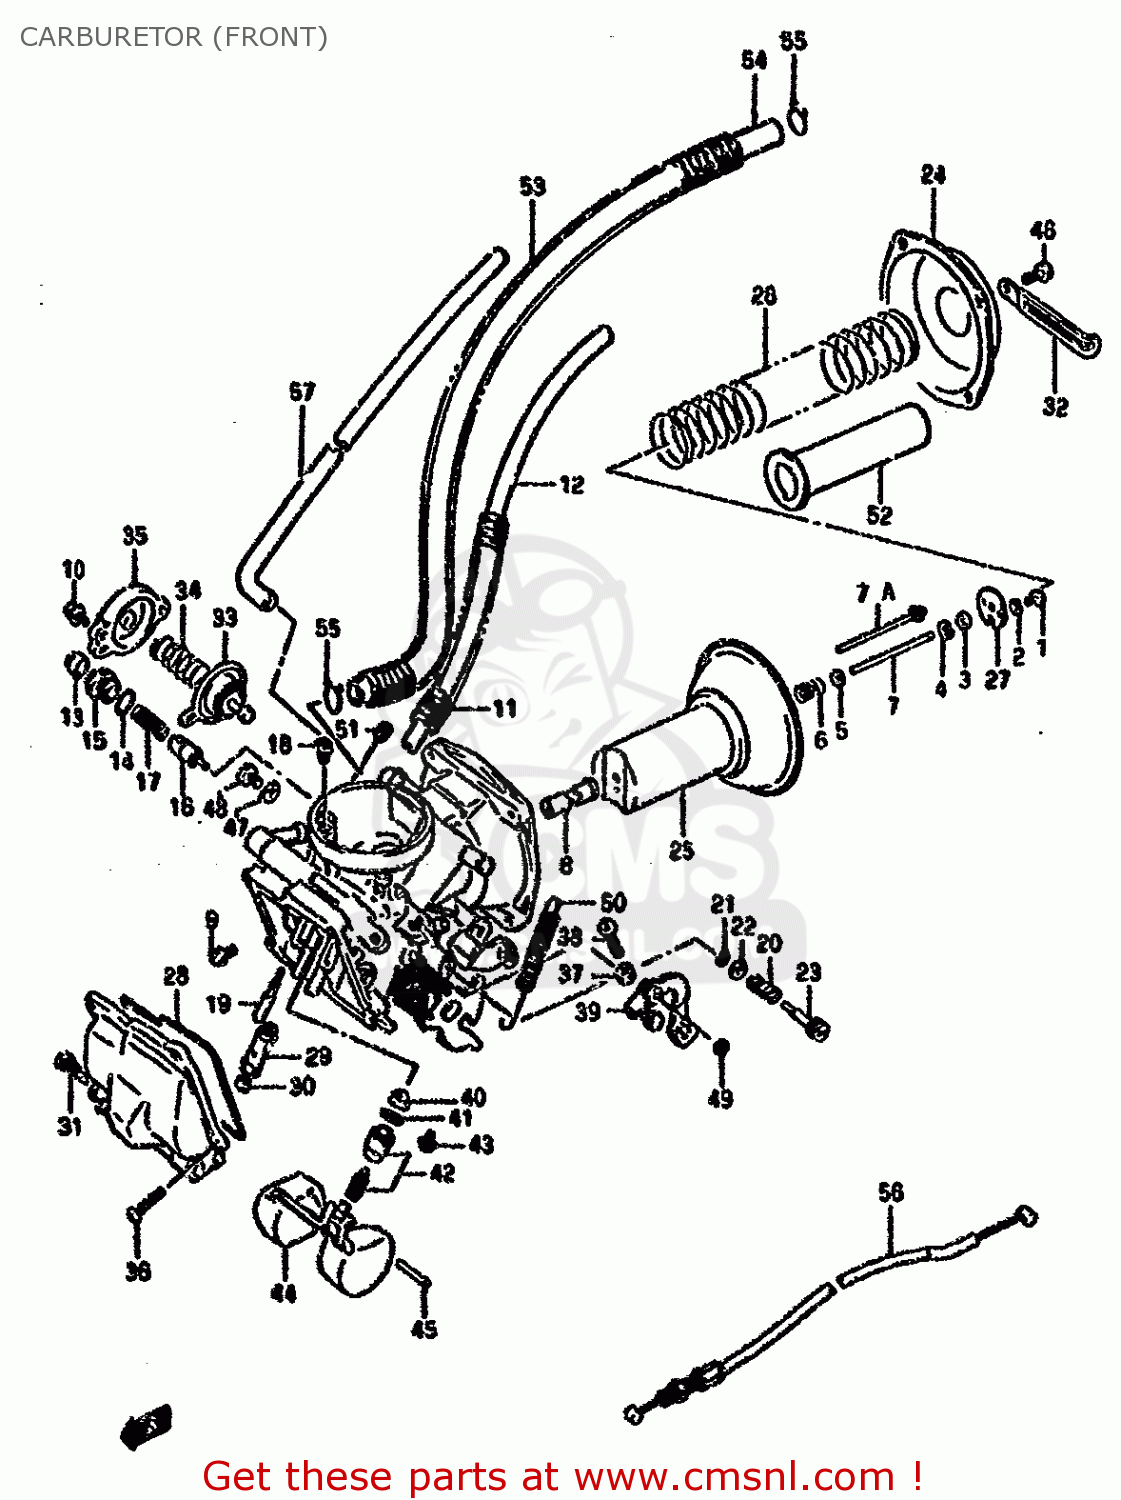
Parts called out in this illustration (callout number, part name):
1	SCREW
2	WASHER,LOCK
3	RING
4	CLIP
5	WASHER
6	SPRING
7	NEEDLE,JET (5D64)
7A	NEEDLE,JET (5D64)
8	JET,NEEDLE (P-6)
9	SCREW
10	SCREW
11	HOSE
12	HOSE(5X8.2X600)
13	CAP
14	O RING
15	HOLDER,GUIDE
16	PLUNGER,STARTER
17	SPRING
18	JET,AIR(65)
19	JET,PILOT(40)
20	SPRING
21	O RING,PILOT AIR SCREW
22	WASHER
23	SCREW,PILOT
24	COVER
25	DIAPHRAGM SET
26	SPRING,DIAPHRAGM
27	PLATE
28	O RING,FLOAT CHAMBER
29	HOLDER,MAIN JET
30	JET,MAIN
31	SCREW,DRAIN
32	CLAMP
33	DIAPHRAGM ASSY
34	SPRING
35	COVER
36	SCREW
37	NUT
38	SCREW
39	LEVER ASSEMBLY
40	FILTER
41	O-RING,NEEDLE VALVE
42	VALVE ASSY,NEEDLE
43	SCREW
44	FLOAT
45	PIN,FLOAT
46	SCREW
47	GASKET,DRAIN PLUG (NAS)
48	SCREW
49	E RING
50	SPRING
51	JET,AIR(1.2)
52	RING
53	HOSE
54	HOSE(6.5X11.5X600)
55	CLAMP
56	CABLE,IDLE SYNCRO
57	HOSE ASSY
